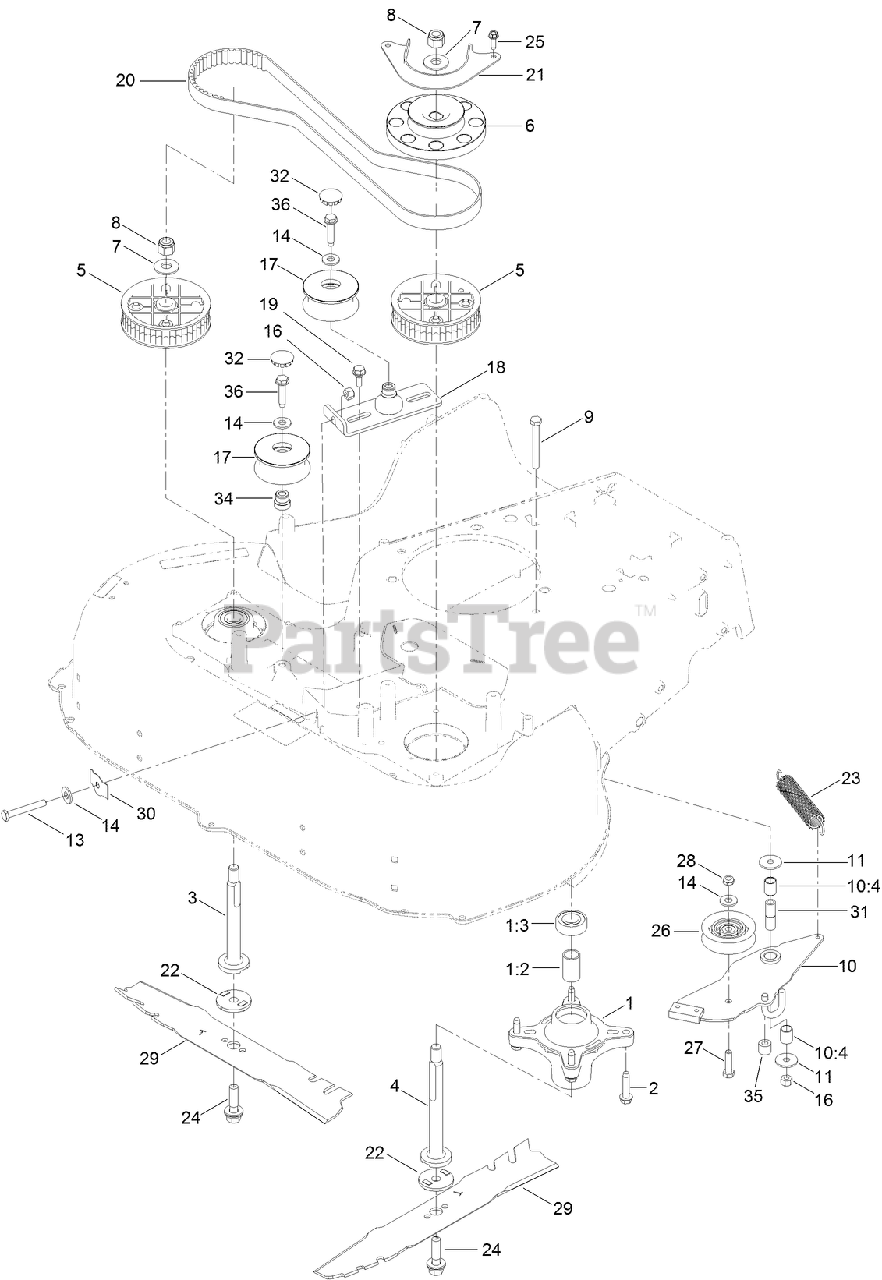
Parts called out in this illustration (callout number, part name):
1	SPINDLE ASM
1:2	SPACER
1:3	BEARING-BALL
2	SCREW-HWH
3	SHAFT-SPINDLE
4	SHAFT-SPINDLE
5	SPROCKET
6	PULLEY-BRAKE, SPINDLE
7	WASHER-SPRING
8	NUT-HEX
9	SCREW-HH
10	BRAKE ARM ASM
10:4	BUSHING-SLEEVE
11	WASHER-PIVOT
13	BOLT-TAP, HH
14	WASHER-FLAT
16	NUT-LOCK, NI
17	PULLEYS AND IDLER KIT
18	BRACKET-IDLER
19	SCREW-SHOULDER,HWH
20	BELT-SYNCHRONOUS
21	GUIDE-BELT, SPINDLE
22	ADAPTER-BLADE
23	SPRING-EXTENSION, BRAKE
24	BOLT-BLADE
25	SCREW-HWHTF
26	PULLEY-IDLER
27	SCREW-HH
28	NUT-LOCK, NI
29	BLADE-ROTARY
30	SPRING-FLAT
31	SPACER-BRAKE
32	PLUG-BUTTON
34	ADAPTER-BORE
35	HOSE-COOLANT
